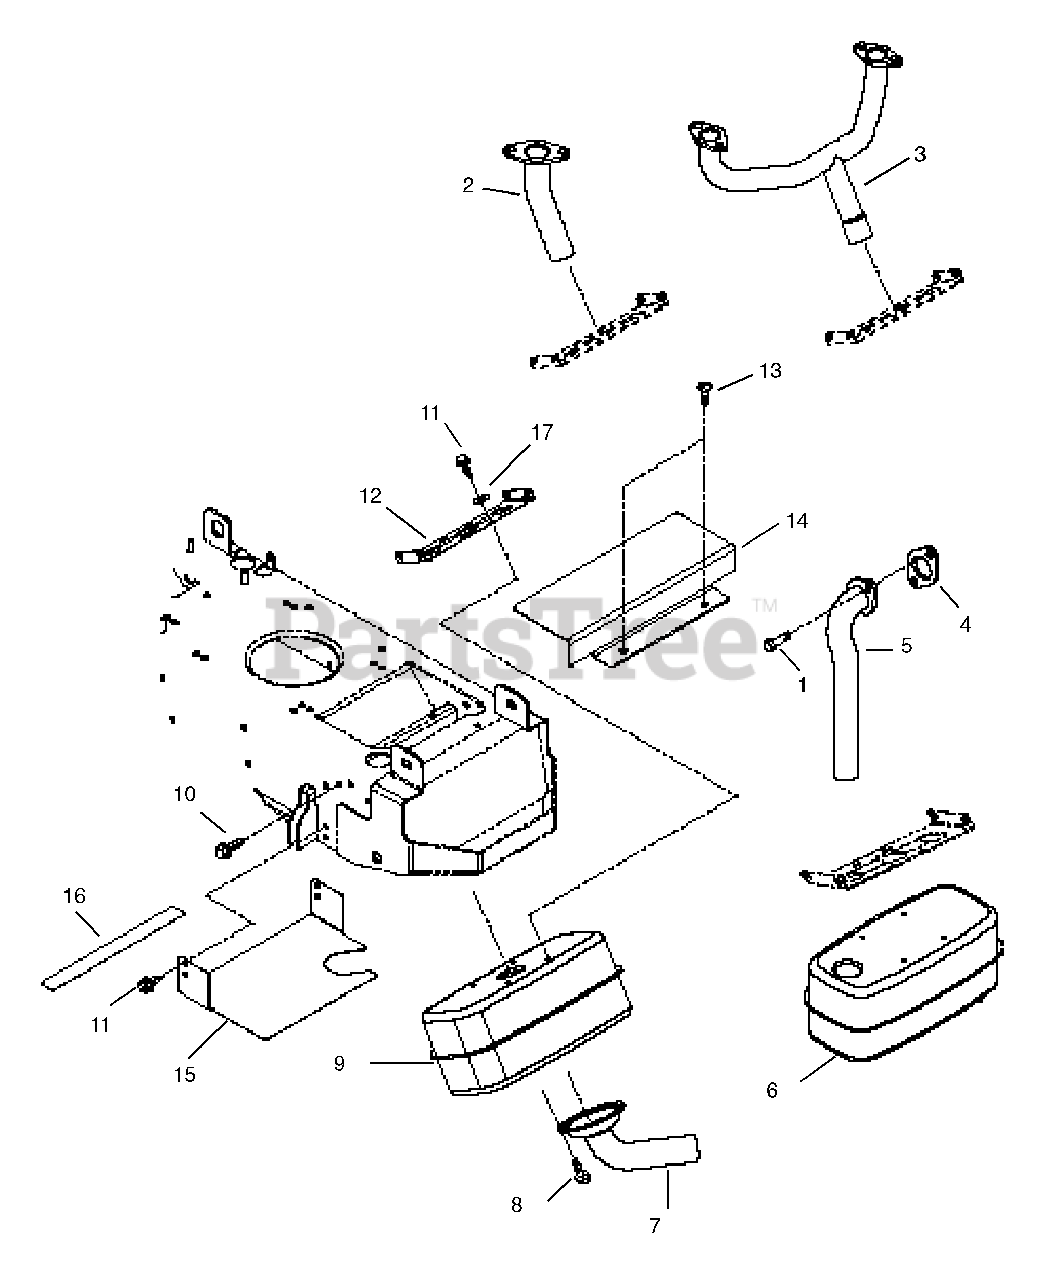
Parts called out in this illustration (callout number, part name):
1	Screw-Cap .31-18 x .75
2	Pipe-Exhaust
3	Pipe-Exhaust Twin B & S
4	Gasket B & S
5	Pipe Exhaust
6	Muffler w/Deflector
7	Deflector-Exhaust
8	Screw-Tapping 8-32 x .38
9	Muffler-Exhaust
10	Screw-Tapping .312-18 x .50
11	Screw-Tapping 12-24 x .75
12	Bracket-Muffler
13	Screw-Tapping .312-18 x .50
14	Shield-Heat
15	Shield-Heat
16	Heat Shield-Fabric 1 x 10.75
17	Washer-Flat-Steel .250 x .562 x .049
